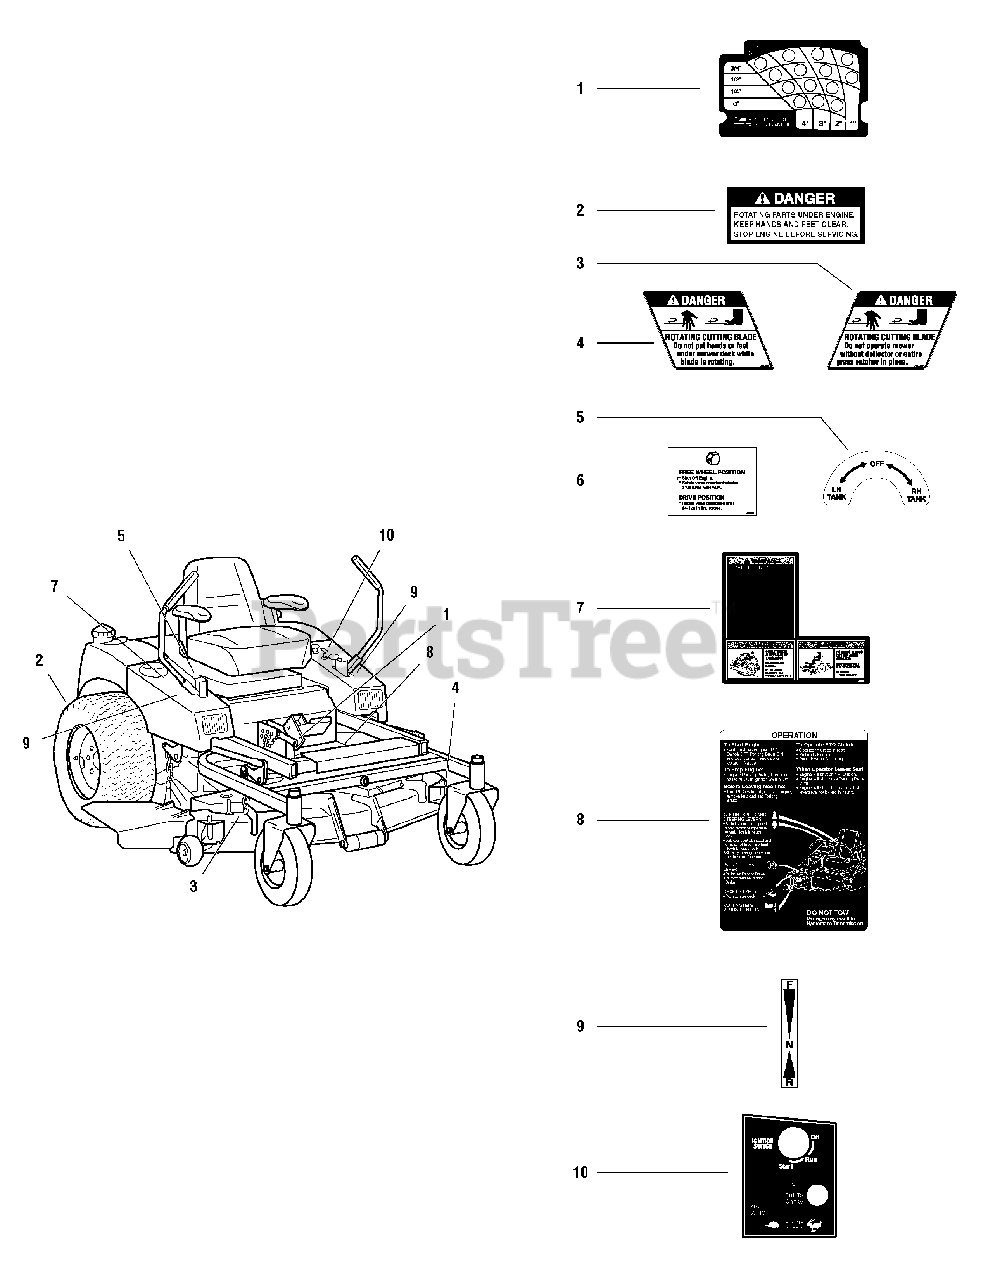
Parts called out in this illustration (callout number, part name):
1	DECAL, Deck Height
2	DECAL, Danger (located on lower frame rail)
3	DECAL, Danger (Chute In Place)
4	DECAL, Danger (Hand Under Deck)
5	DECAL, Fuel Shut Off
6	DECAL, Hydro Release Valve (located under seat, near LH pump)
7	DECAL, Warning/Danger
8	DECAL, Operation
9	DECAL, Direction Control
10	DECAL, Instrument Panel
